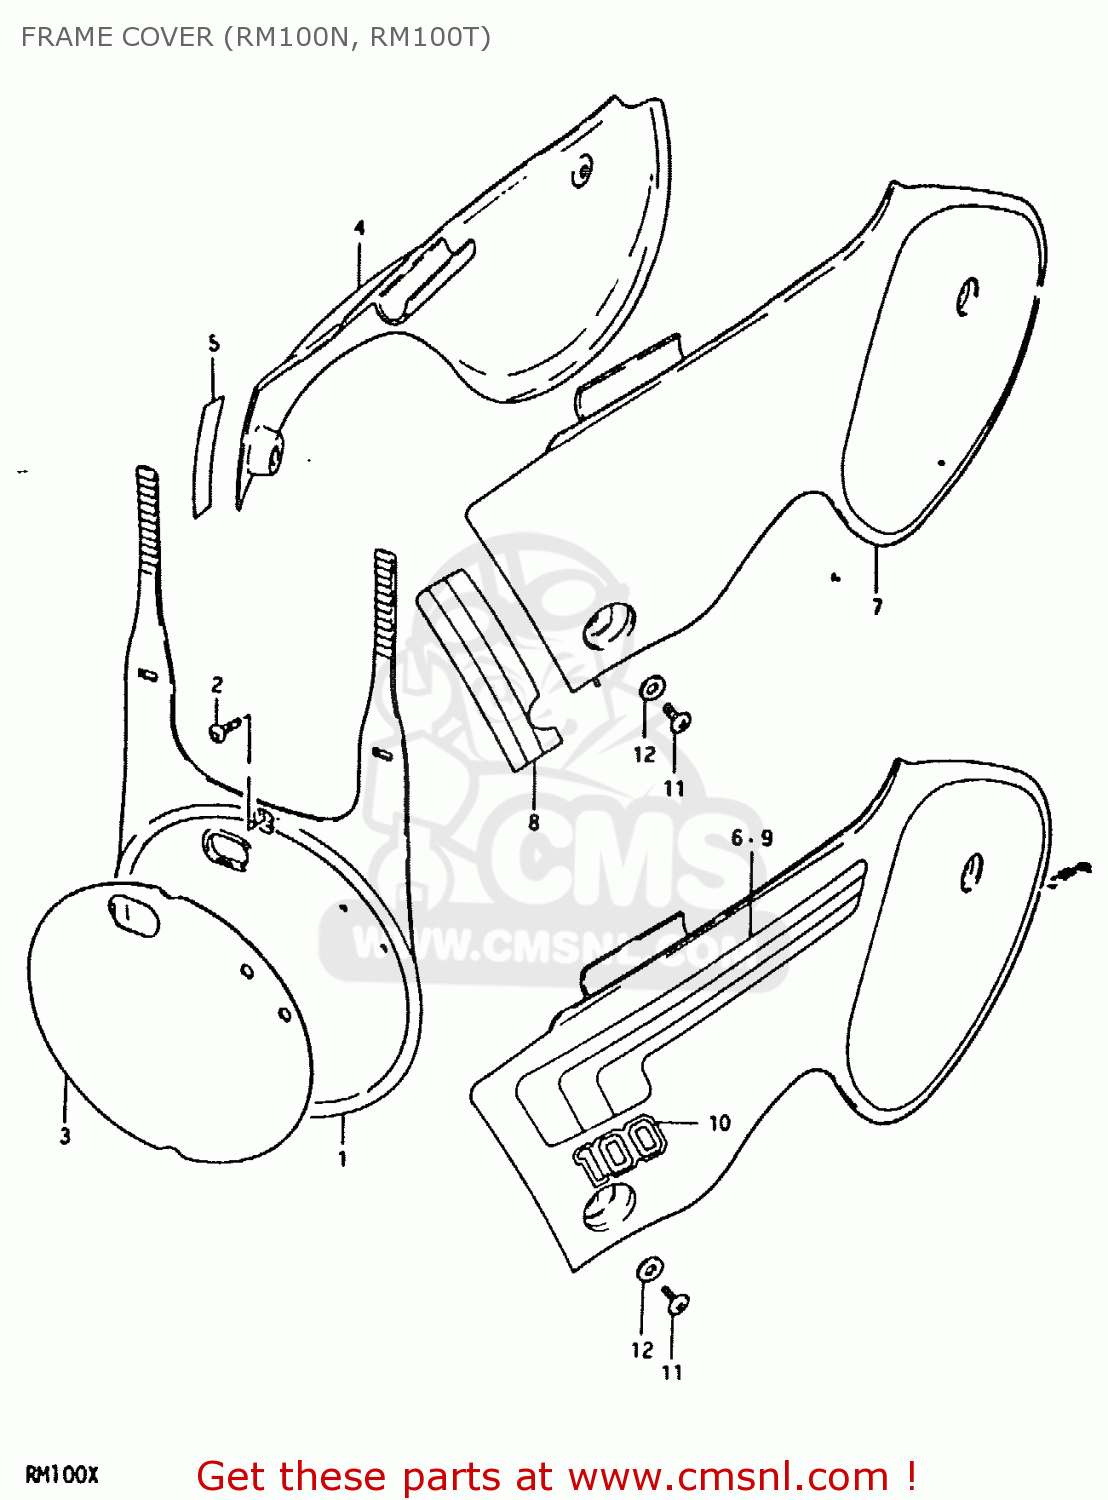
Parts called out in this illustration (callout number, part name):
1	PLATE,FR NUMBER
2	(5X20) CROSS SCREW
3	EMBLEM,FRONT NUMBER PLATE
4	COVER,FRAME,RIGHT
5	TAPE, RH
6	TAPE,FRAME COVER
7	COVER,FRAME,L(YELLOW)
8	TAPE,FRAME COVER,LEFT STRIPE
9	TAPE,FRAME COVER
10	EMBLEM
11	SCREW 6X12
12	WASHER
